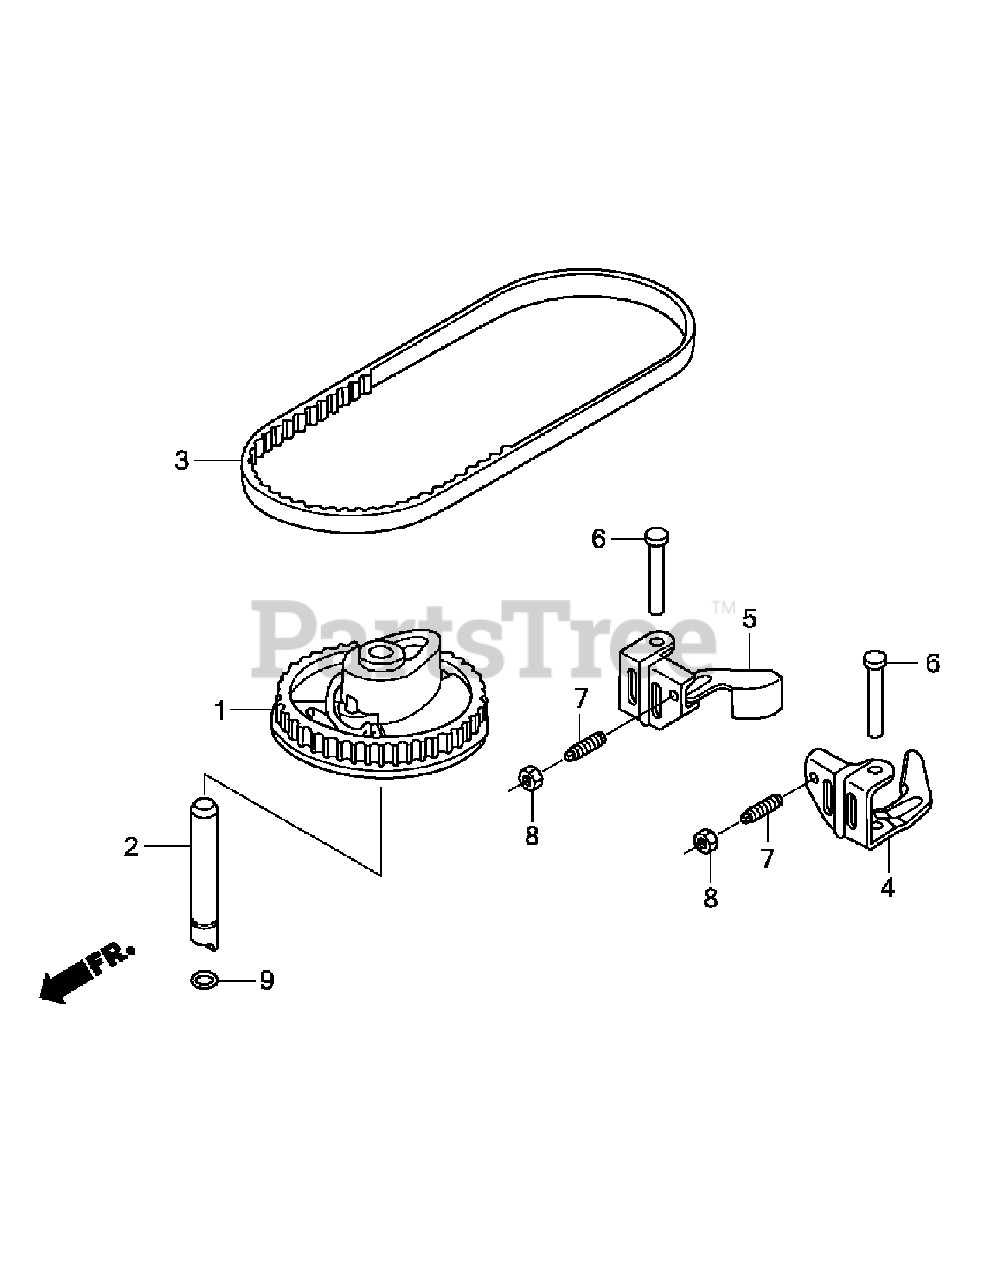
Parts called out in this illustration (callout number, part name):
1	Pulley, Camshaft.
2	Shaft, Cam Pulley
3	Belt, Timing (84hu7 G-200)
4	Arm, In. Valve Rocker
5	Pri; Arm, Ex. Valve Rocker
6	Shaft, Rocker Arm
7	Screw, Tappet Adjusting
8	Nut, Tappet Adjusting.
9	O-ring (6.8x1.9) (Arai).
